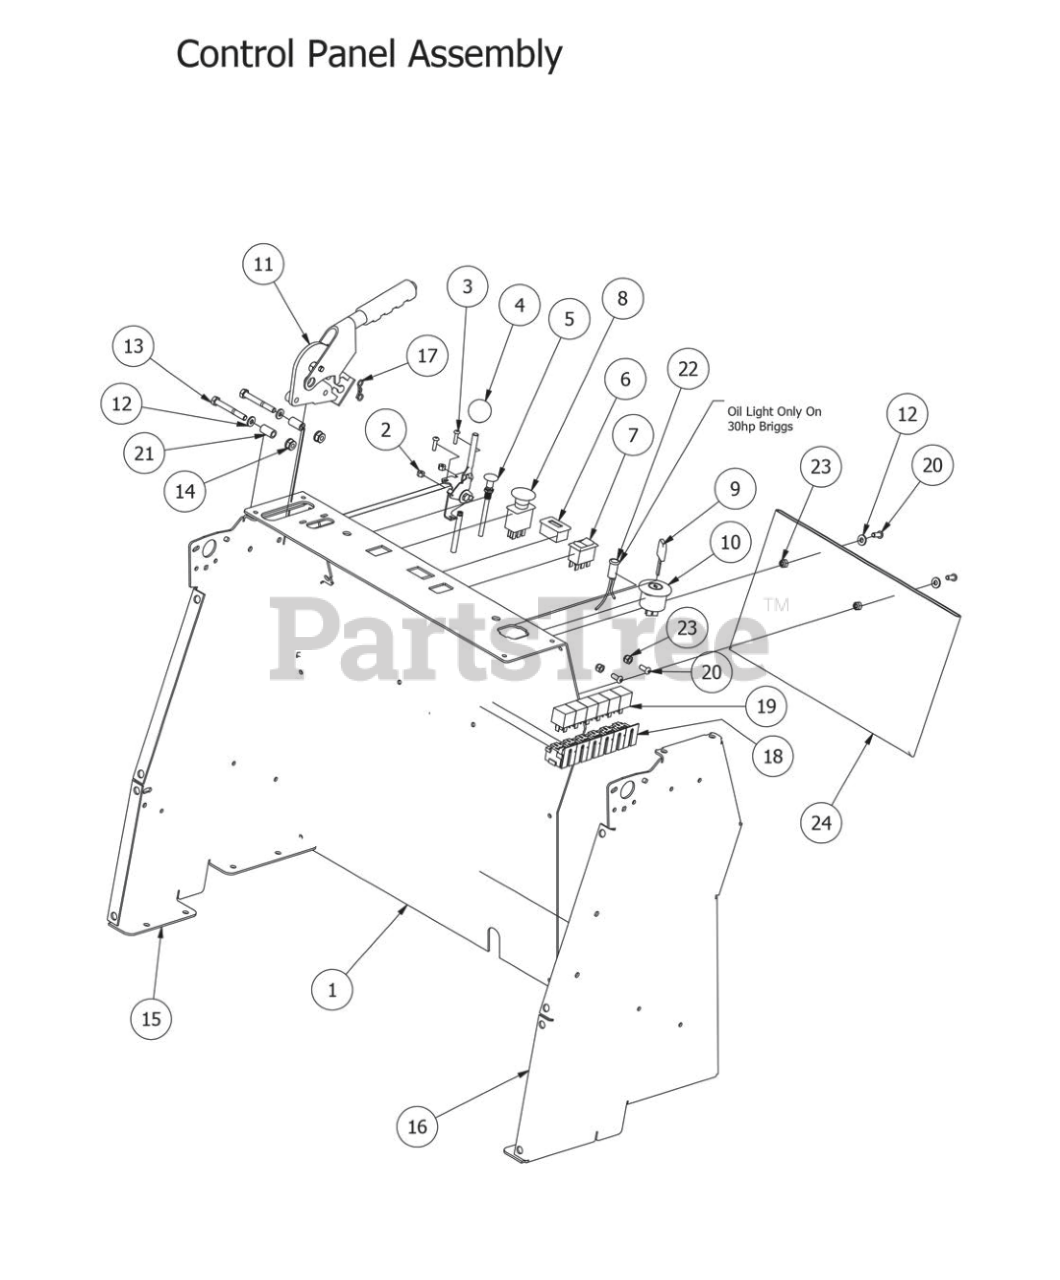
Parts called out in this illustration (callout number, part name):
1	Podium Front Panel
2	10-24 Nylon Insert Locknut
3	10-24 x 1 BS C/S 18-8 SS
4	Throttle-All Outlaws
6	Tachometer
7	Rocker Deck Lift Switch - 2011
8	PTO Engager
9	Ignition Key
10	Ignition Switch
11	Brake Handle-Stand On
12	1/4" Flat Washer
13	5/16" x 2 1/2" Bolt
14	5/16-18 Nylon Flange Nut
15	Podium Panel Left Side
16	Podium Panel Right Side
18	Wiring Harness-Stand on Models
19	Relay Terminal
20	1/4" x 5/8" BS C/S 18-8 SS
21	Brake/Latch Spacer-Stand On
23	1/4" Nylock Nut
24	Trash Collection Bag Bandit Stand On
